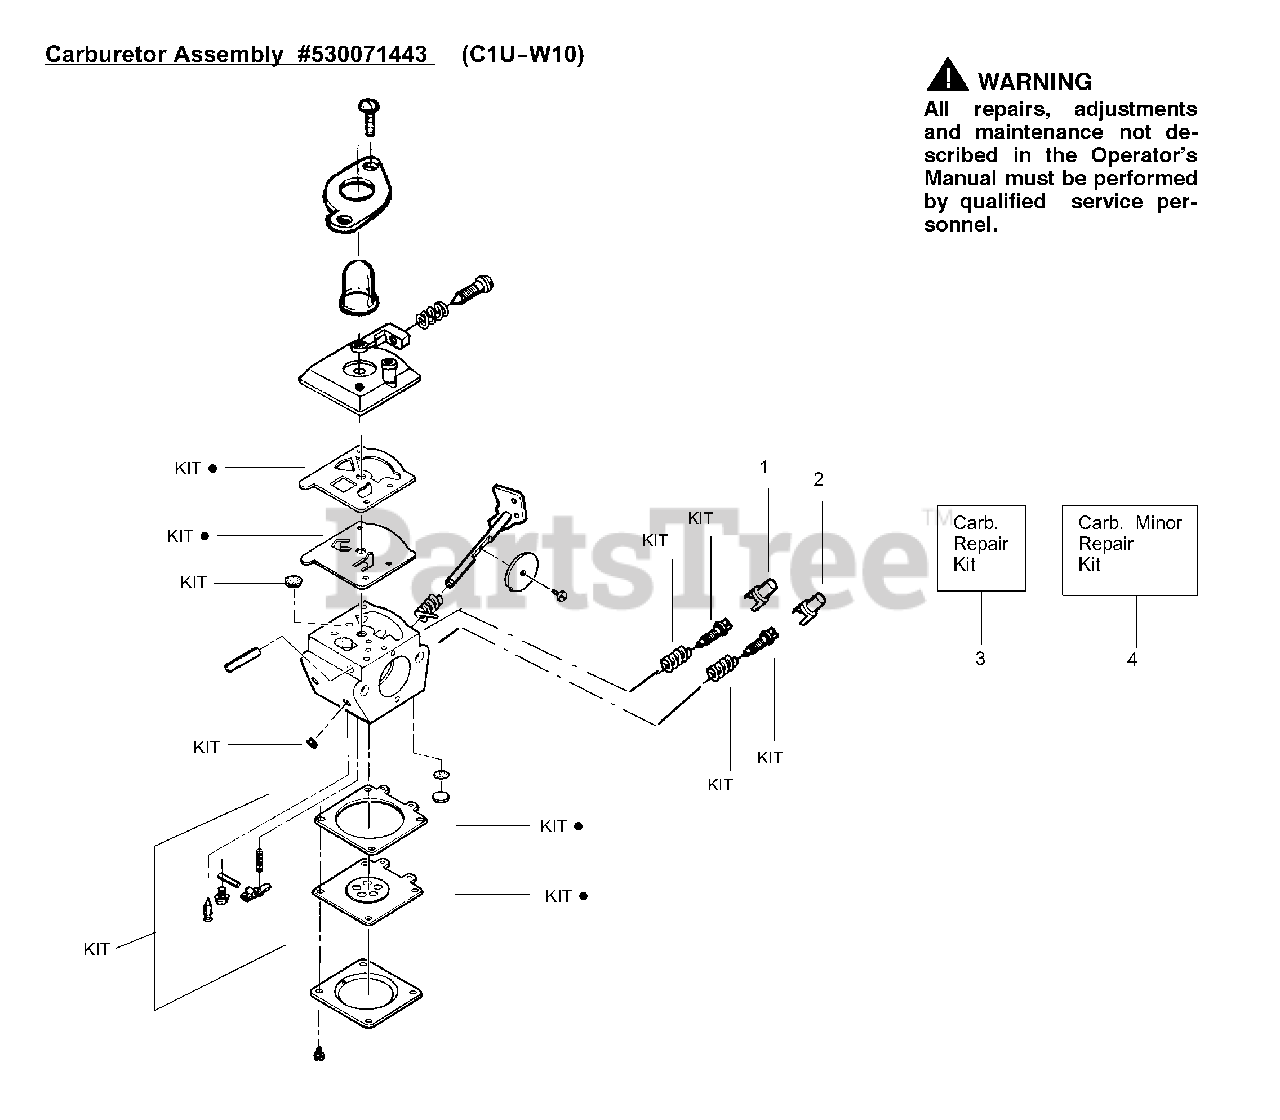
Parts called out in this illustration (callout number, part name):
1	Limiter Cap (low)
2	Limiter Cap (high)
3	Kit--Carburetor Repair
4	Kit--Carburetor Minor Repair
530071443	Carburetor Assembly (C1U-W10)
